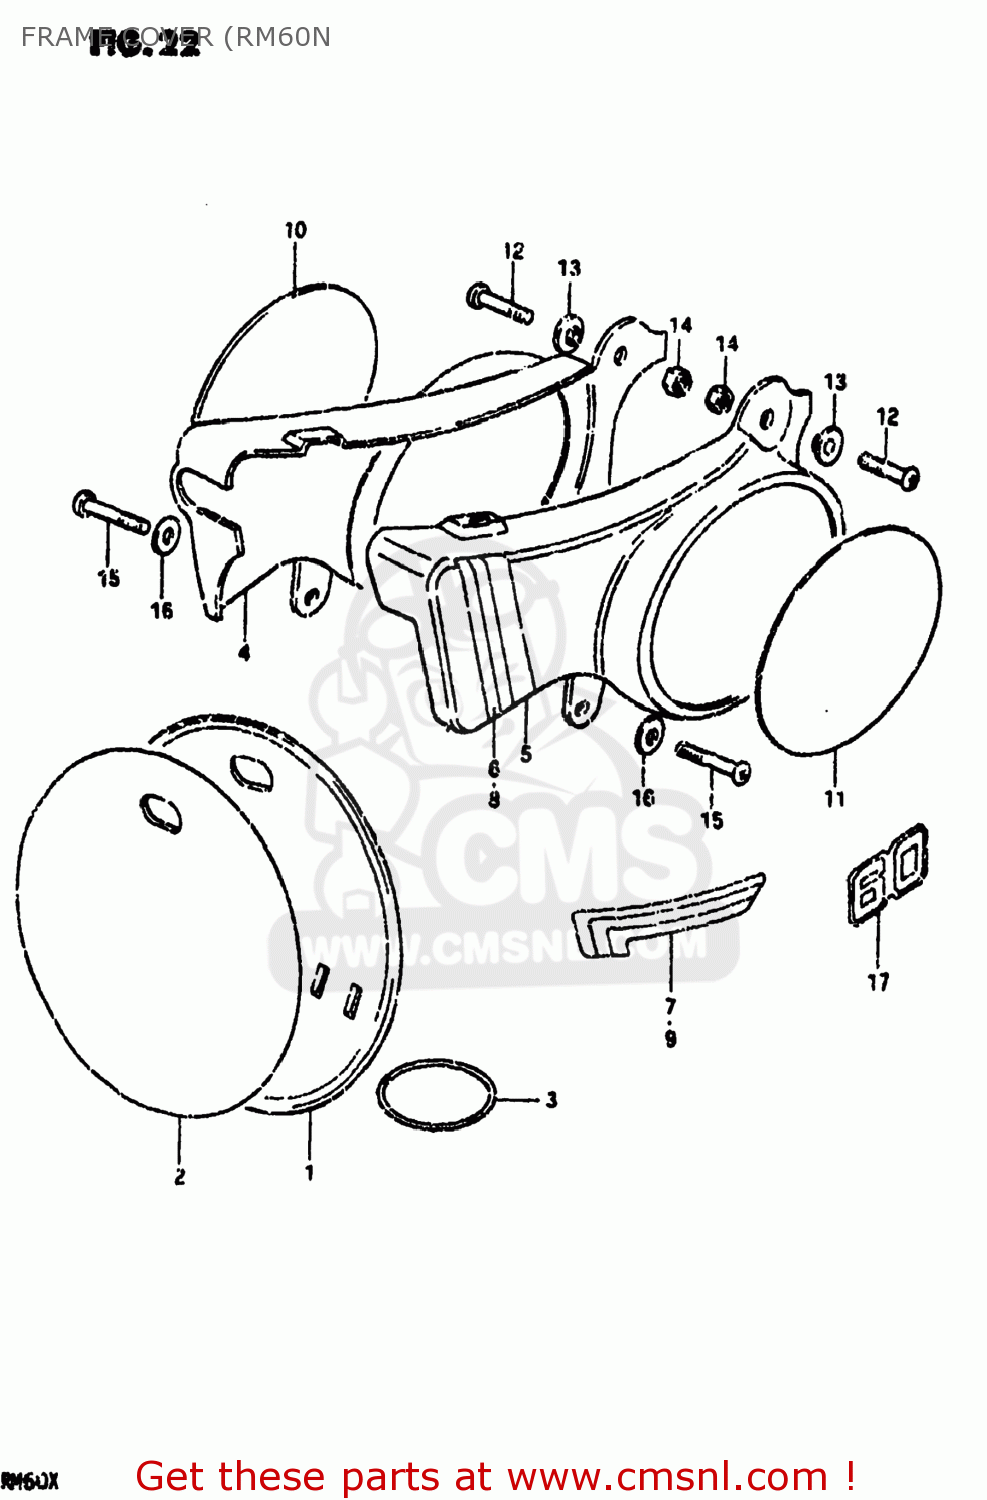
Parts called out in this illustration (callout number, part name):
1	PLATE,NUMBER,FRONT
2	EMBLEM,FRONT NUMBER PLATE
3	O-RING
4	COVER,FRAME,RIGHT
5	COVER,FRAME,LEFT
6	TAPE,FRAME COVER
7	TAPE,FRAME COVER
8	TAPE,FRAME COVER
9	TAPE,FRAME COVER
10	TAPE,FRAME COVER NUMBER PLATE
11	LABEL,FRAME COVER
12	SCREW
13	WASHER
14	NUT
15	SCREW
16	WASHER
17	EMBLEM
